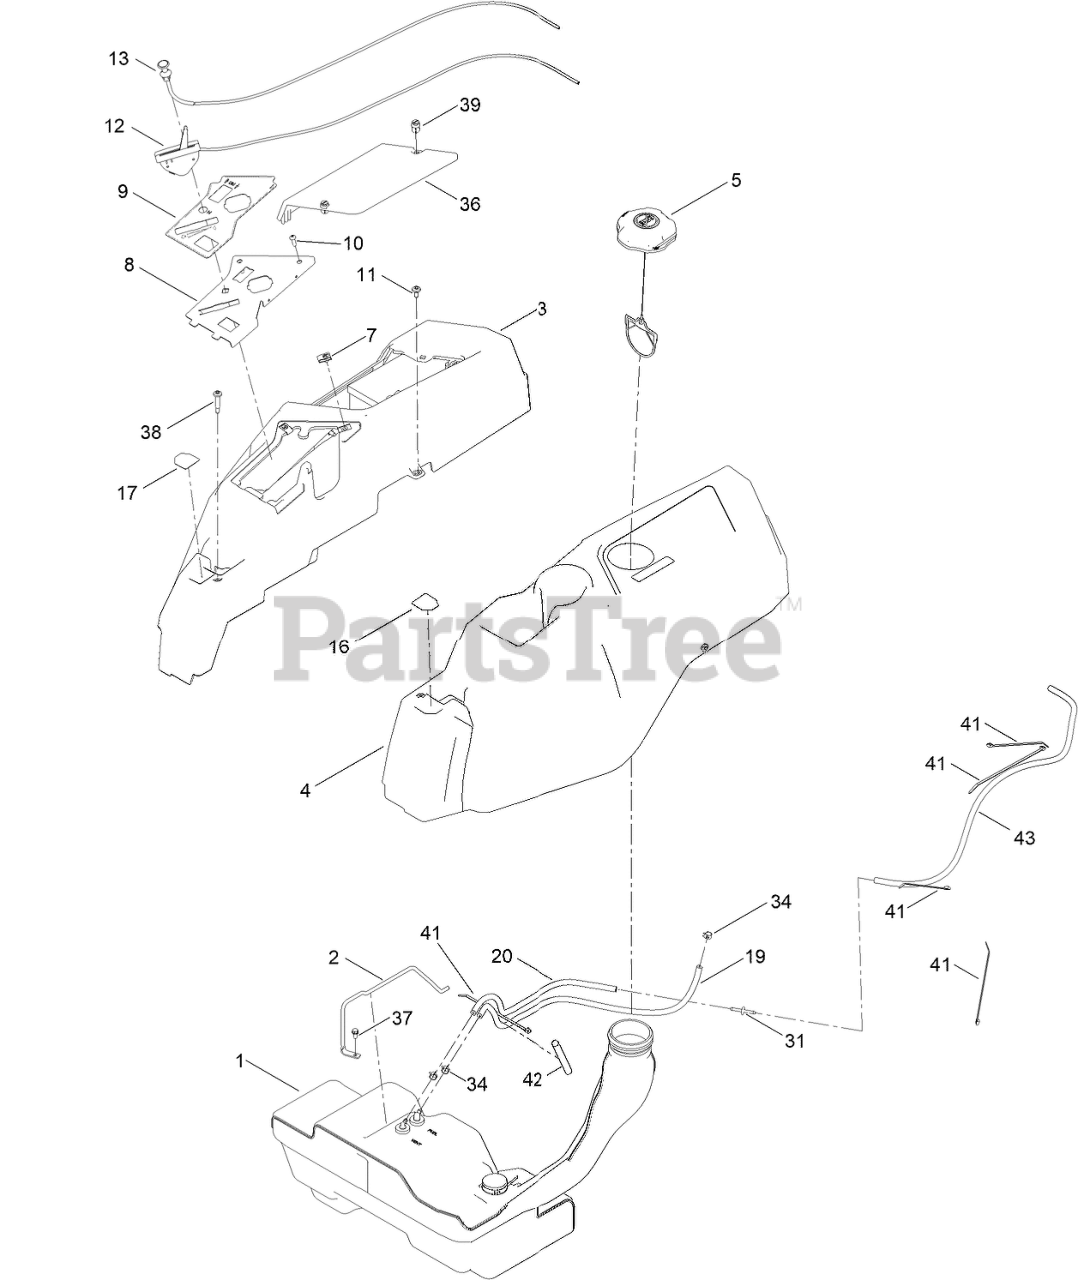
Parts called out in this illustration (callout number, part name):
1	TANK-FUEL ASM
2	ROD-HOLD DOWN
3	POD-RH
4	POD-LH
5	CAP-FUEL, RATCHETING
8	PANEL-CONTROL
9	DECAL-PANEL, CONTROL
10	SCREW-PRH
11	SCREW-SHOULDER
12	CABLE-THROTTLE
13	CABLE-CHOKE
16	DECAL-LEVER, CONTROL (LH)
17	DECAL-LEVER, CONTROL (RH)
19	HOSE-FUEL
20	HOSE-VENT
31	ADAPTER ORIFICE
34	CLAMP-HOSE
36	COVER-BATTERY
37	SCREW-HWH
38	SCREW-SHOULDER
39	FASTENER
41	TIE-CABLE
42	SLEEVE-FUEL LINE PROTECTOR
